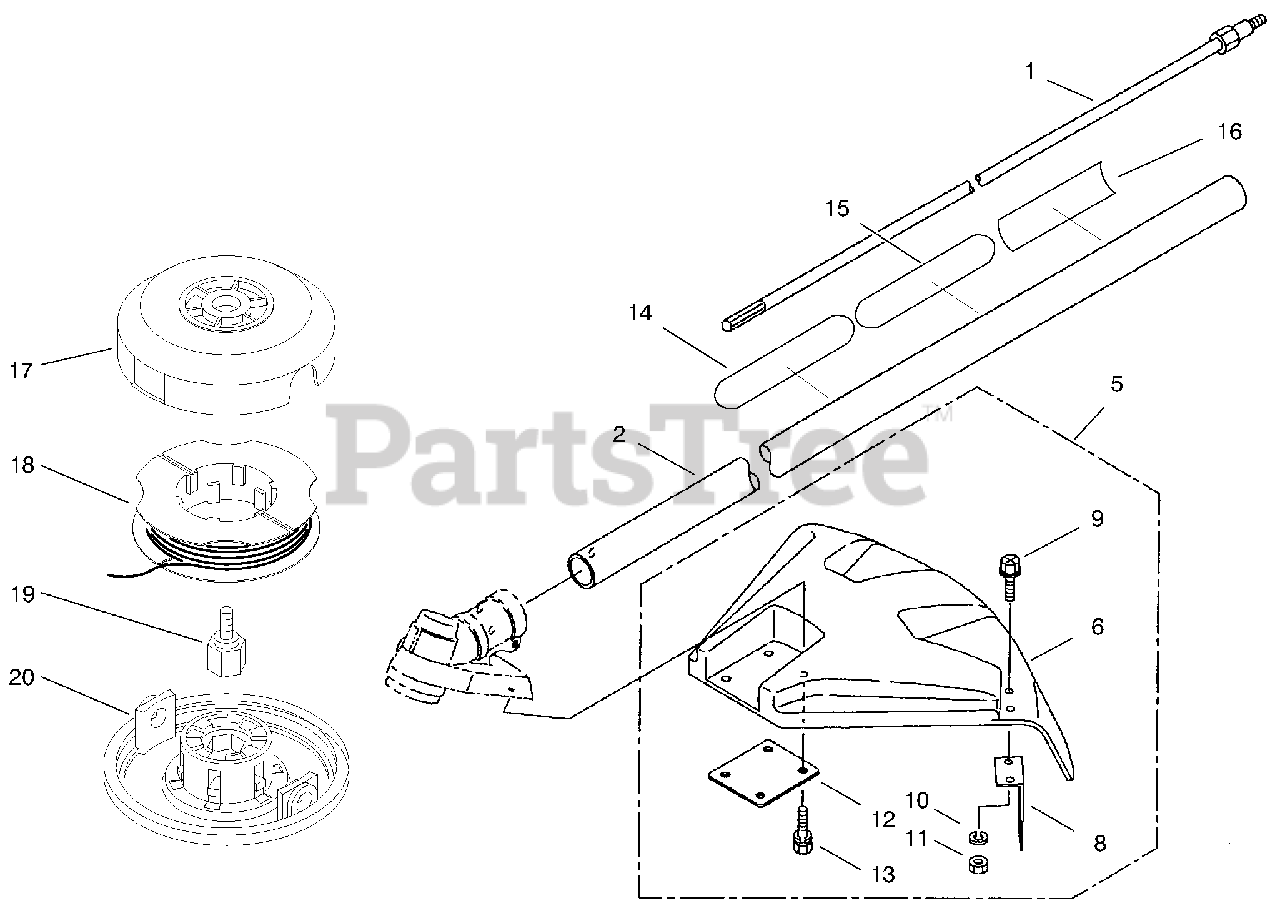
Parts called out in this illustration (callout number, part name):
1	Driveshaft Assembly
2	Driveshaft Tube Assembly (Incl. Ref. # 14,15)
5	Safety Cover Assembly (Incl. Ref. # 6-13)
6	Safety Cover
8	String Cutter
10	Spring Washer
14	Decal-Caution
15	Decal-Caution
16	Decal-Toro
18	Spool with Line
19	Stud-Mounting
20	Base-Indexing
